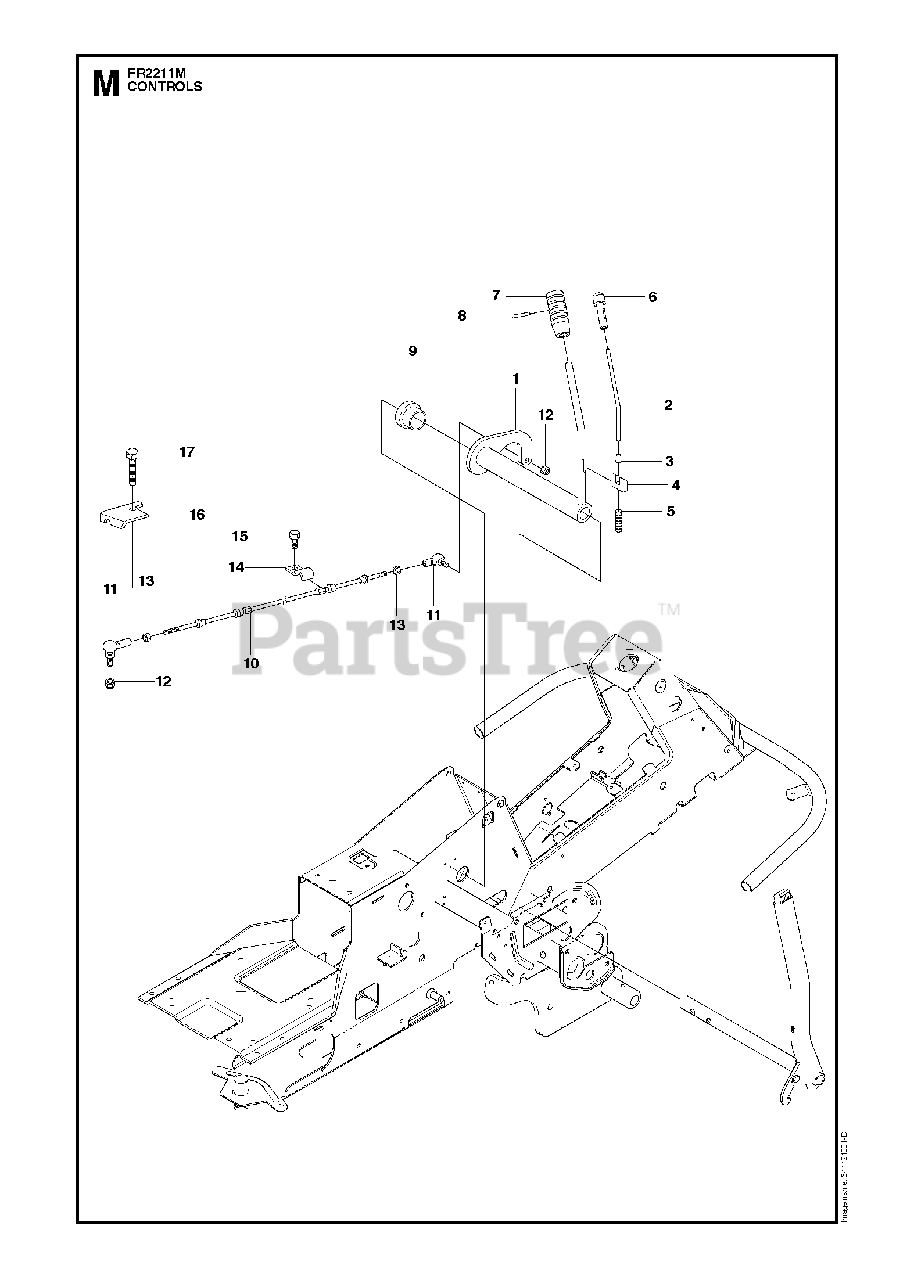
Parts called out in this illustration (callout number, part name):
3	END PIECE
8	SPRING PIN 3X24
9	BUSH
10	CONTROL CABLE
11	CONNECTOR
12	LOCKNUT M5
